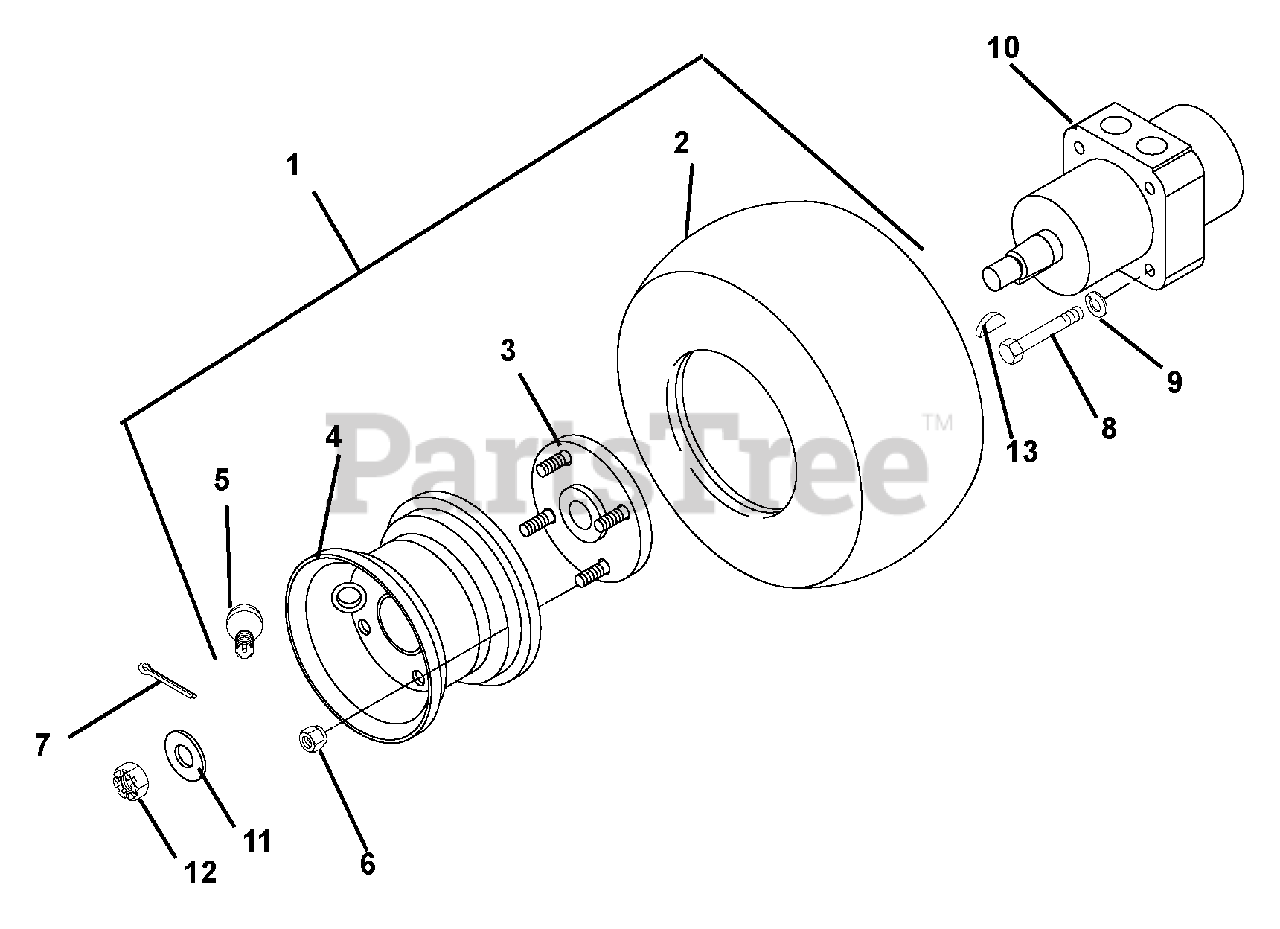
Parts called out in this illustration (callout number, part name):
1	ASSY,WHL & TIRE 18X850
2	TIRE, 18X850-8 4PLY
3	ASSY, HUB W/STUDS
4	ASSY, WHEEL
5	VALVE STEM ASS'Y
6	NUT-LUG .50-20 YWZC
7	@PIN-CTR .12X1.25 EXTPRSQCT YZ
8	@BLT-HEX .38-16X1.00 GR5 YWZC
9	@WSHR-LK .38X.094 REG YWZC
10	MOTOR, HYD WHEEL
11	WSHR-FL-STL.755X1.375X.062YWZC
12	NUT,HEX 3/4-28 SLOTTED
13	KEY-WDRF .19X.75 HRD #9
